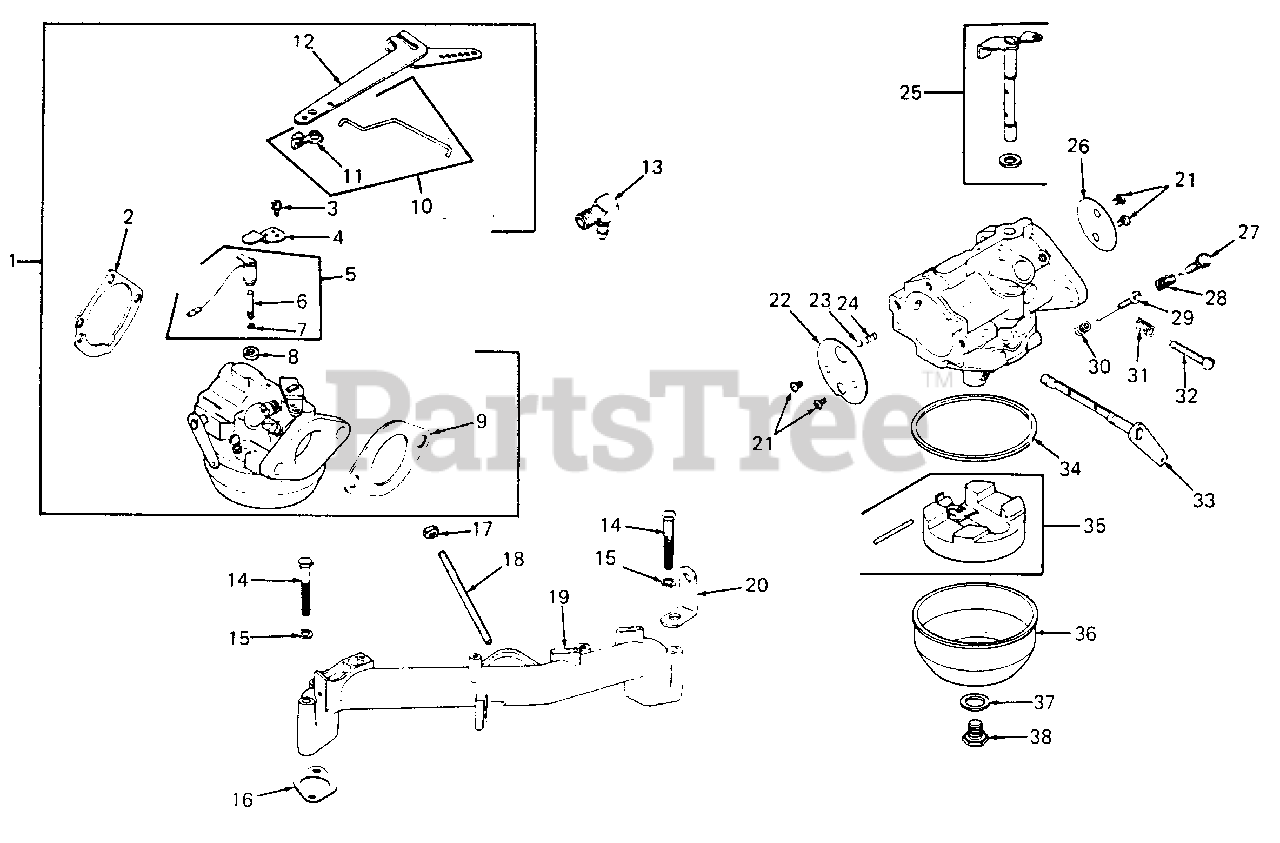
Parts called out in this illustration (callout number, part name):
1	Kit, Carburetor w/Linkage
2	Gasket, Air Cleaner Elbow
4	Bracket, Solenoid
5	Kit, Solenoid
6	Rod, Plunger
8	Gasket, Needle Seat
9	Gasket, Carburetor
10	Kit, Governor Linkage
11	Bushing, Governor Linkage
12	Arm, Governor
13	Connector, Hose
14	Screw, HC 5/16-18 X 2-3/4
15	Washer, Lock, 5/16
16	Gasket, Intake Manifold
17	Nut, Hex Jam, 5/16-18
18	Stud, 5/16-18 X 1
19	Manifold, Intake
20	Strap, Lifting
21	Screw, Throttle & Choke Plate
22	Plate, Choke
23	Ball, Choke Friction
24	Spring, Choke Friction
25	Shaft, Throttle w/Lever & Seal
26	Plate, Throttle
27	Needle, Idle Fuel Adj
28	Spring, Idle Fuel
29	Needle, Main Fuel
30	Spring, Main Fuel
31	Spring, Idle Speed
32	Screw, Idle Speed Adj
33	Lever, Choke
34	Gasket, Bowl
37	Gasket, Bowl Retainer Screw
38	Screw, Bowl Retainer
